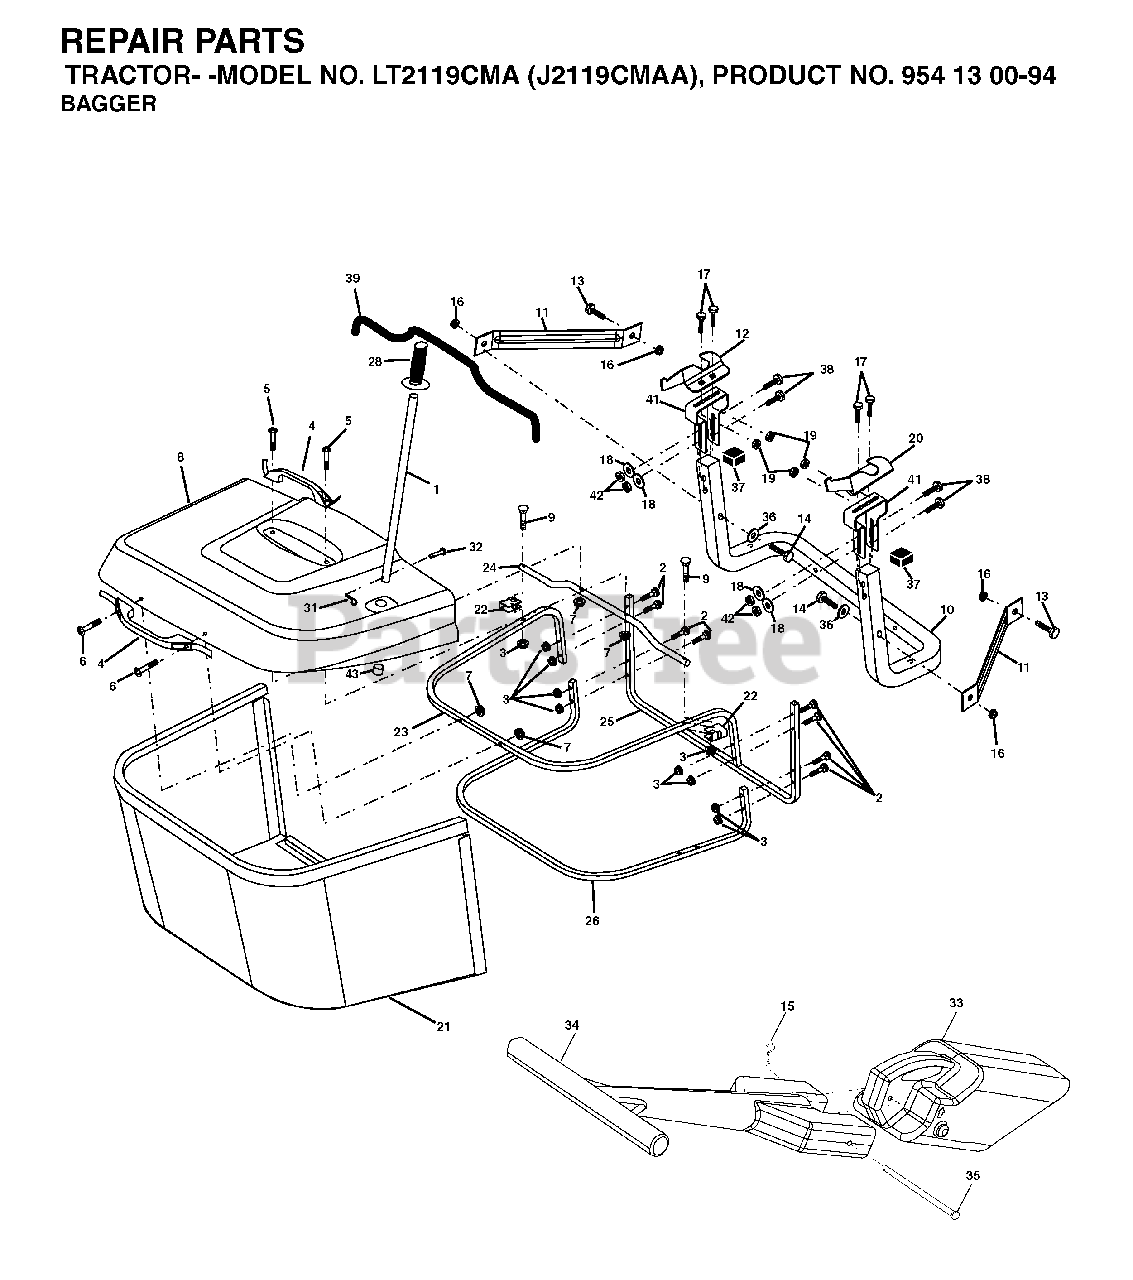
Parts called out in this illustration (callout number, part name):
1	TUBE HANDLE
3	NUT T
5	SCREW.PAN.HEAD
11	BRACKET
14	BOLT-HEX EAK
15	RETAINER-SPRNG RB
16	NUT LOCK FLG 3/8-16 UNC
17	BOLT
18	WASHER M
19	NUT LOCK HEX FLANGE 5/16-18
20	BRACKET
21	GRASS BAG
22	BRACKET
23	TUBE
24	TUBE
26	TUBE
28	GRIP.HANDLE.BLACK
31	RETAINER M
32	RIVET,DRILLED
33	MULCH PLUG, CTH150
35	PIN
36	WASHER
38	BOLT.5/16-18X2.5
41	BRKT, BAGGER
42	NUT.71038.31-18.HEX.NYLOCK
43	PLUG, TUBING END
